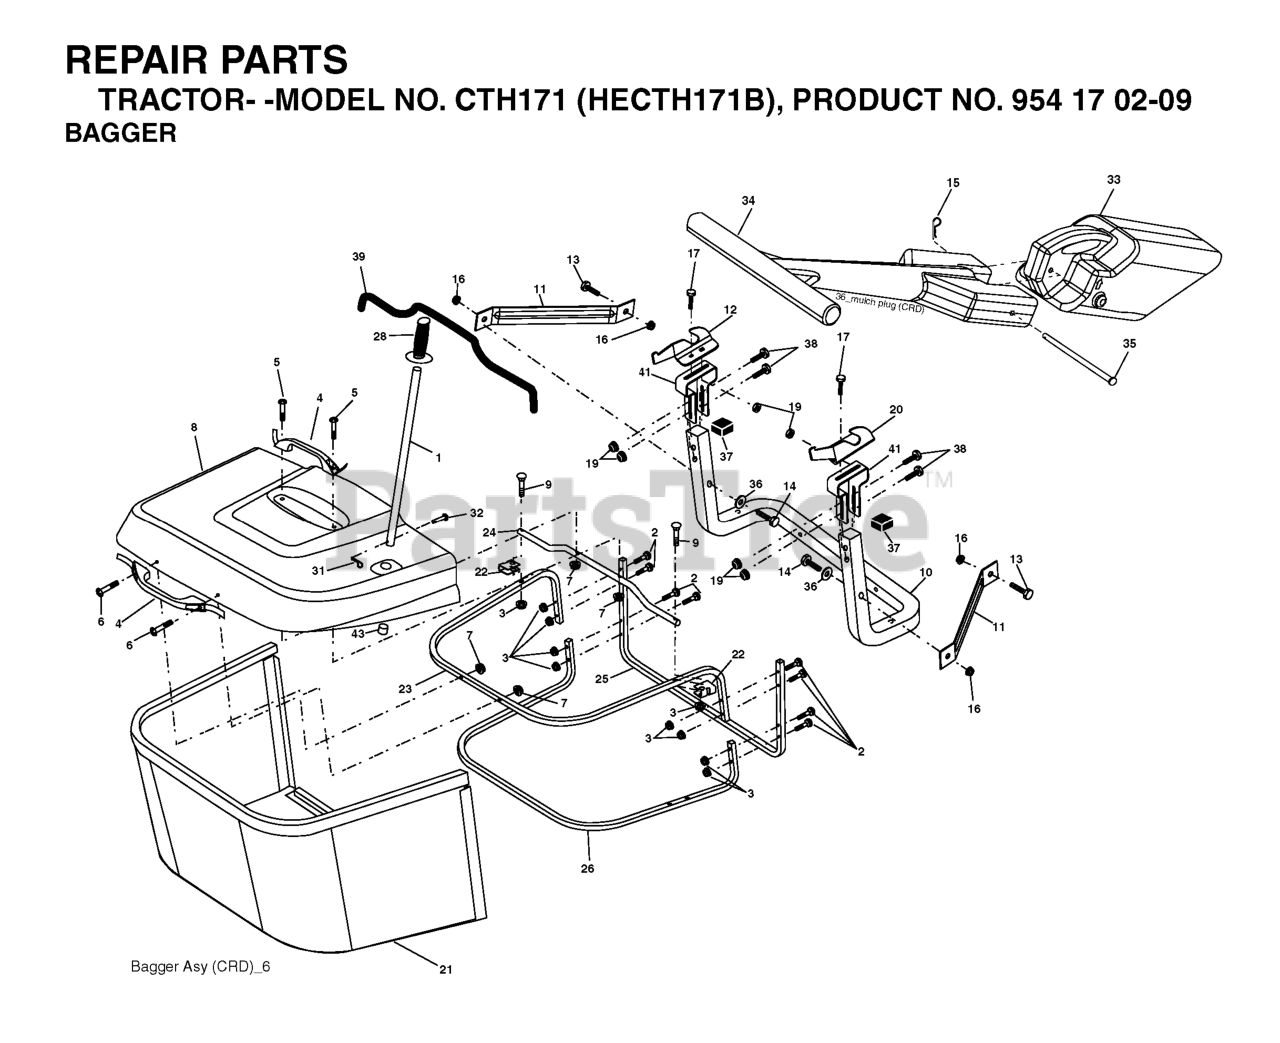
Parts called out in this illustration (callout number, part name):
1	TUBE HANDLE
2	Bolt Carriage 1/4-20 x 2.0 Gr.5
3	NUT T
4	HANDLE.BAGGER.W/LVRS.BLK.CRD
5	SCREW.PAN.HEAD
6	REPL BY 532 75 00-29
8	COVER.PNT.BGR.CRD.WSLOTS.MS668
9	Bolt Carriage 1/4-20 x 2.25d x Gr.5
10	TUBE
11	BRACKET.SUPPORT.UPPER.BAG.CRD
12	BRKT PIVOT
13	BOLT
14	BOLT-HEX EAK
15	RETAINER-SPRNG RB
16	NUT LOCK FLG 3/8-16 UNC
17	RP BOLT 5/16-18 X3/4 ZN/YEL GR
19	NUT LOCK HEX FLANGE 5/16-18
20	BRKT.PIVOT.RH.CRD
21	GRASS BAG
22	BRKT.SIDE.BAG.CRD
23	TUBE.UPPER.BAG.CRD
24	TUBE.PIVOT.BAG.CRD.BLACK
26	TUBE.LOWER.BAG.CRD
28	GRIP.HANDLE.BLACK
31	RETAINER CLIP
32	RIVET,DRILLED
33	PLUG.MULCHER.92 CRD
34	HANDLE.MULCHER.92.CRD (2 2)
36	WASHER
37	Plug Support Bagger CRD
38	BOLT.5/16-18X2.5
39	SEAL.TRIM.37'
41	BRKT.VERT.ADJ.BAGGER.CRD
43	PLUG, TUBING END
